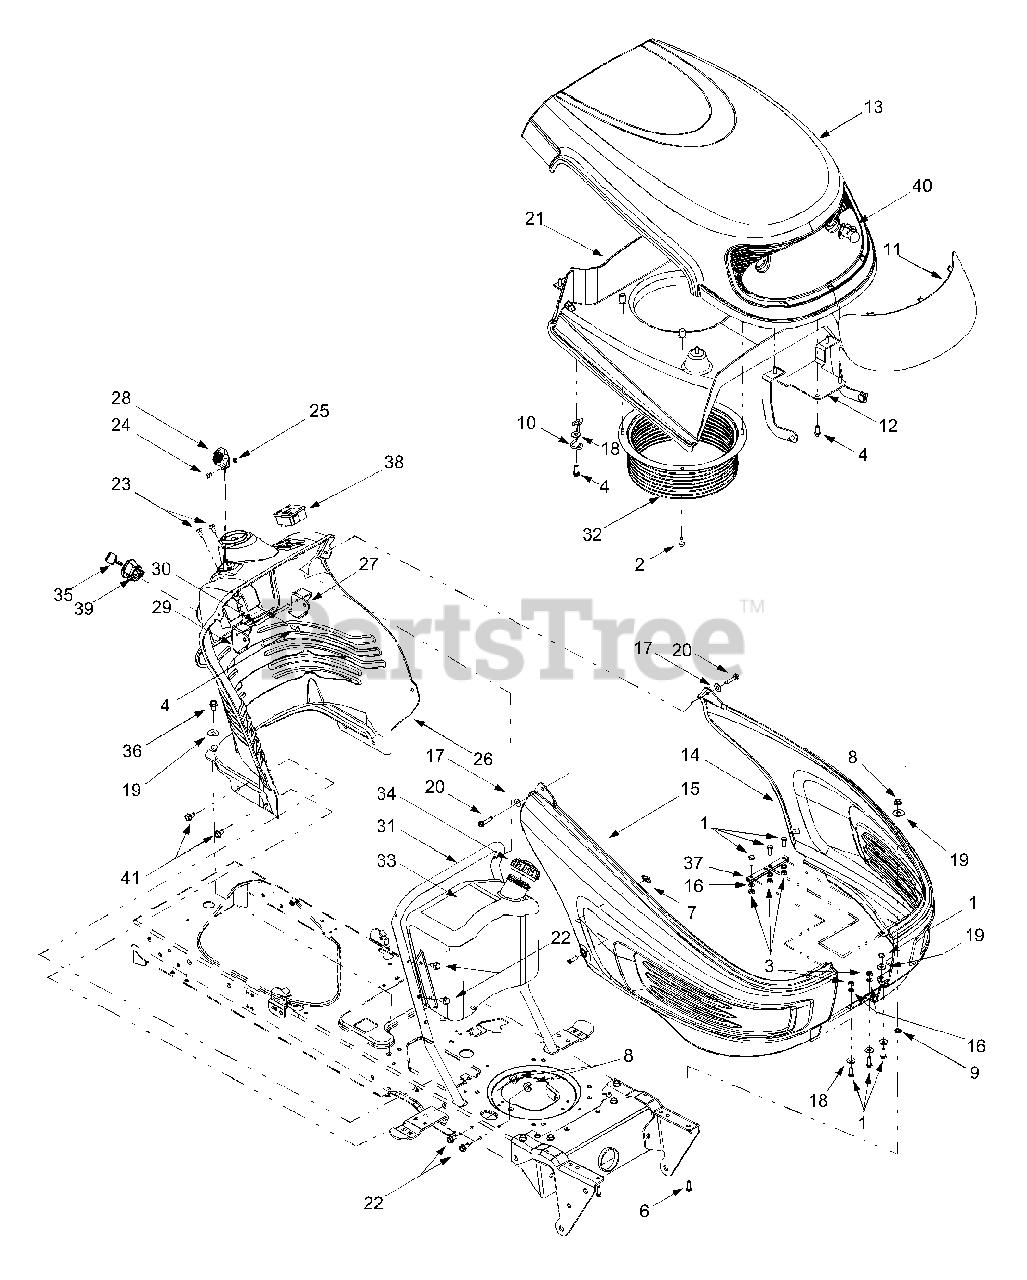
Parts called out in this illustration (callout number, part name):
1	Hex Cap Screw, 1/4-20 x .75
2	Self-tapping Screw, 1/4-20 x .5
3	Hex Nut, 1/4-20
4	Self-tapping Screw, 1/4-15 x .75
6	Hex Cap Screw, 5/16-18 x 1.0
7	U-type Speed Nut, 1/4-20
8	Flange Lock Nut, 5/16-18
10	Hood Latch Rod
11	Head Light Lens
14	LH Side Panel
15	RH Side Panel
16	Lock Washer, 1/4
17	Flat Washer, .283 x .75 x .030
18	Flat Washer, .28 x .74 x .063
19	Flat Washer, .349 x 1.0 x .063
20	Self-tapping Screw, 1/4-20 x 1.25
21	Hood Plenum w/o Intake Bellow
22	Self-tapping Screw, 5/16-18 x .625
23	Torx Self-tapping Screw, 1/4-14 x .625
24	Torx Screw, #8-32 x .375
25	Hex Nut, 8-32
26	Dash Panel, 4-style
27	Parking Brake Button
28	Throttle Control Lever
29	Cruise Control Button
30	Brake/Cruise Pivot Rod
33	Fuel Tank, 2-gallon
34	Fuel Cap
35	Ignition Key w/ plastic cover
36	Self-tapping Screw, 5/16-18 x .75
39	Ignition Switch
40	Headlight Assembly
41	Self-tapping Screw, 5/16-18 x .75
